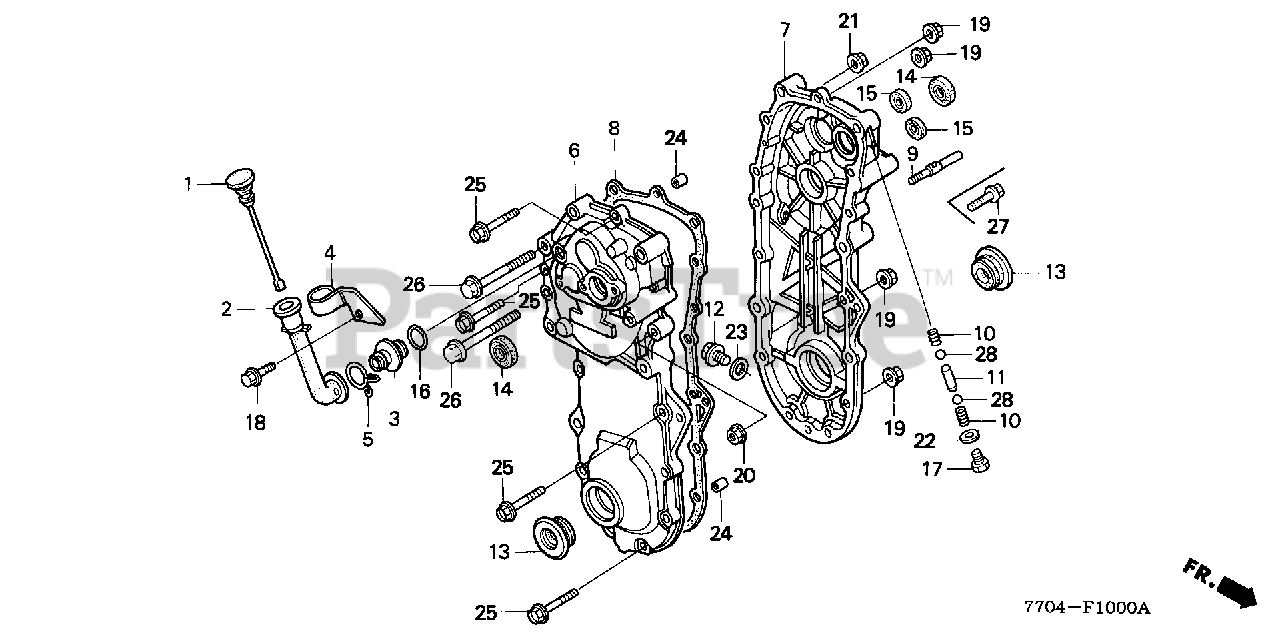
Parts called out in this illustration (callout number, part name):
1	DIPSTICK, OIL
2	PIPE, OIL FILLER
3	JOINT, OIL PIPE
4	STAY, OIL PIPE
5	CLIP, AIR HOSE (20.5MM)
6	CASE, R. TRANSMISSION
7	CASE, L. TRANSMISSION
8	GASKET, TRANSMISSION CASE
10	SPRING, BALL SETTING
11	PIECE, INTERLOCK
12	BOLT, DRAIN PLUG (12X15)
13	SEAL, WATER (25X46X8.5)
14	OIL SEAL (17X30X8)
15	OIL SEAL (12X22X6)
16	O-RING (16MM)
17	BOLT, HEX. (8X10)
18	BOLT-WASHER (6X16)
19	NUT, FLANGE (6MM)
20	NUT, FLANGE (8MM)
21	NUT, FLANGE (10MM)
22	WASHER, PLAIN (8MM)
23	WASHER, DRAIN PLUG (12MM)
24	PIN, DOWEL (8X14)
25	BOLT, FLANGE (6X35)
26	BOLT, FLANGE (10X90)
27	BOLT, FLANGE (8X50)
28	BALL, STEEL (#8) (1/4)
